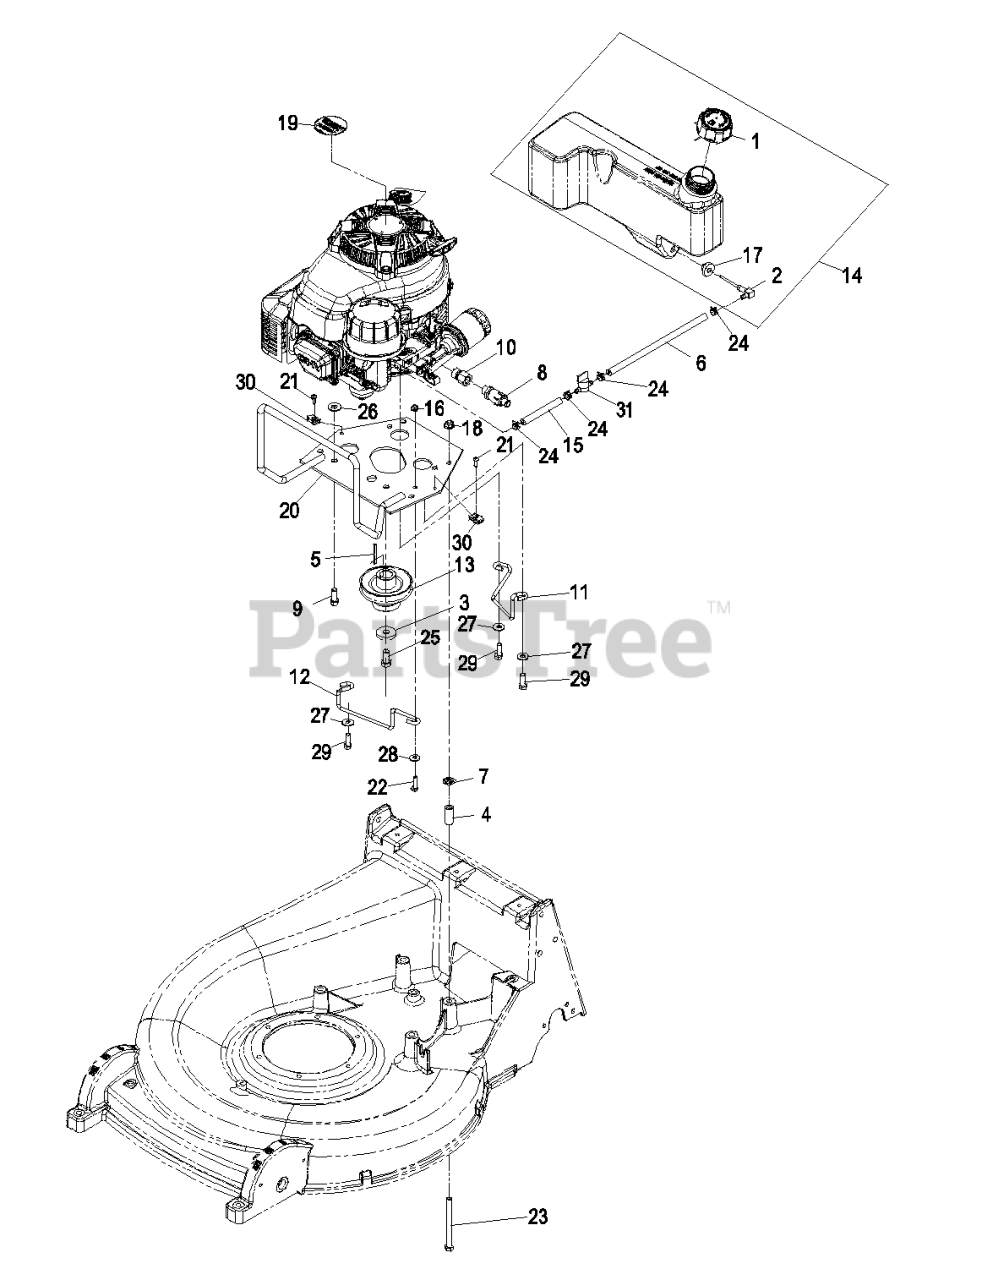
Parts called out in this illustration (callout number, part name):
1	CAP-FUEL
2	ELBOW-TANK, FUEL
3	WASHER-CLUTCH
4	BUSHING-LEVER, LIFT
5	KEY-SQUARE
6	HOSE-FUEL
7	RING-RETAINING
8	VALVE-DRAIN, OIL
9	SCREW-TAPTITE
10	ADAPTER
11	GUIDE-BELT, BLADE
12	GUIDE-BELT, TRANSMISSION
13	PULLEY-ENGINE
14	ASM,FUEL TANK M26 W/CAP
15	HOSE-FUEL
16	NUT-HF
17	BUSHING
18	NUT-HF, NI
22	SCREW-HH
23	SCREW-HH
24	CLAMP-HOSE
25	SCREW-HH
26	WASHER-FLAT
27	WASHER-FLAT
28	WASHER-FLAT
29	SCREW-HH
30	Nut, Retainer-Panel 1/4-20
31	VALVE-FUEL
